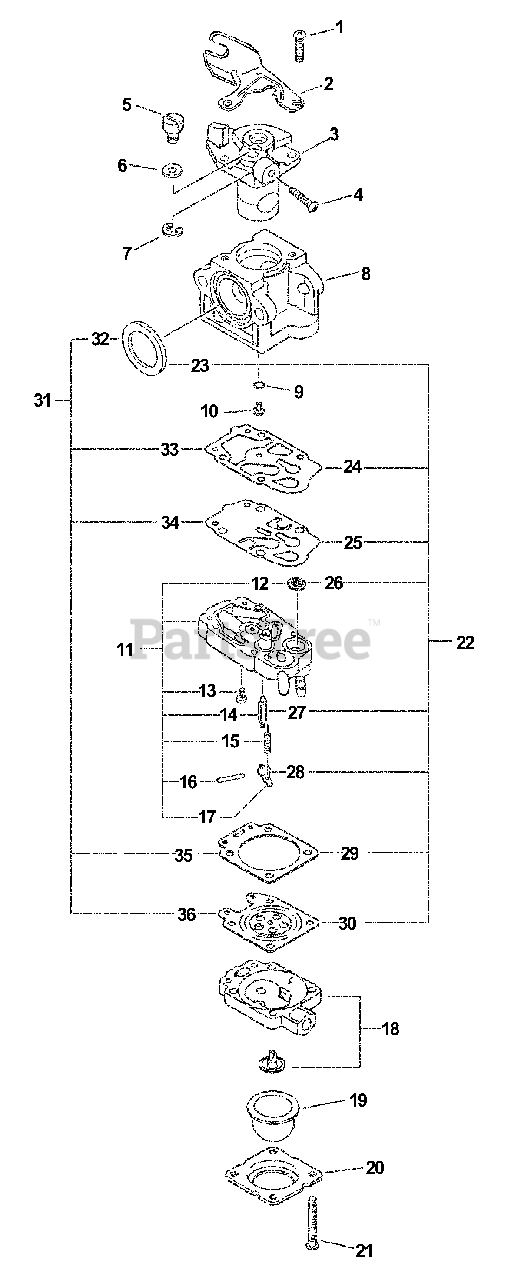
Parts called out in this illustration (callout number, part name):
2	BRACKET, THROTTLE CABLE
3	THROTTLE VALVE ASSY
8	BODY, CARBURETOR
10	JET, MAIN
11	BODY ASSY, PUMP
12	STRAINER
14	VALVE, INLET NEEDLE
15	SPRING, METERING LEVER
16	PIN, METERING LEVER
17	LEVER, METERING
18	BODY ASSY, PURGE
19	BULB, PURGE
20	RETAINER, PURGE BULB
22	REPAIR KIT, CARBURETOR
23	SEAL
24	GASKET, PUMP
25	DIAPHRAGM, PUMP
26	STRAINER
27	VALVE, INLET NEEDLE
28	LEVER, METERING
29	GASKET, DIAPHRAGM
30	DIAPHRAGM, METERING
31	GASKET / DIAPHRAGM KIT
32	SEAL
33	GASKET, PUMP
34	DIAPHRAGM, PUMP
35	GASKET, DIAPHRAGM
36	DIAPHRAGM, METERING
